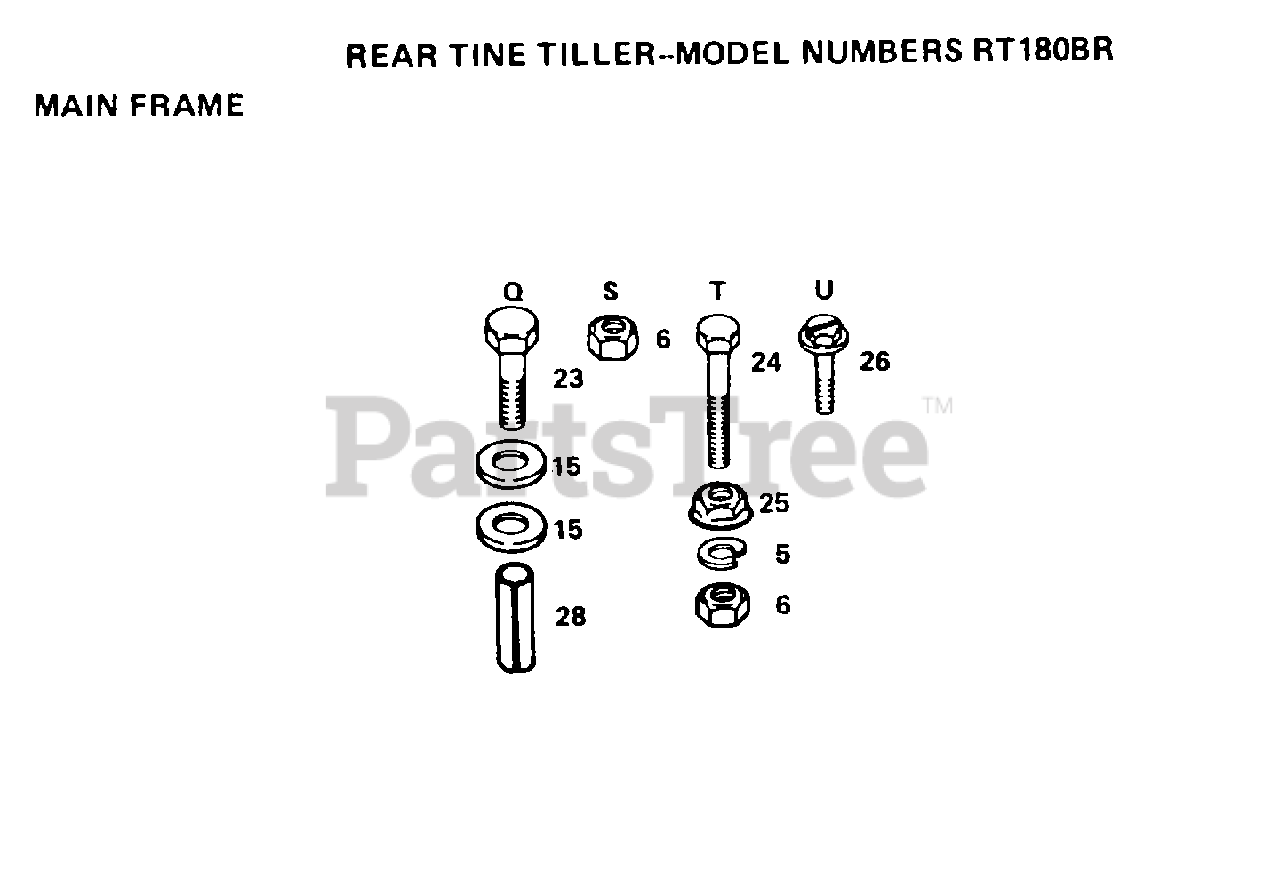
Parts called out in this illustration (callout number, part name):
5	LOCKWASHER
6	NUT.HEX.3/8-16UNC
26	SCREW TI
